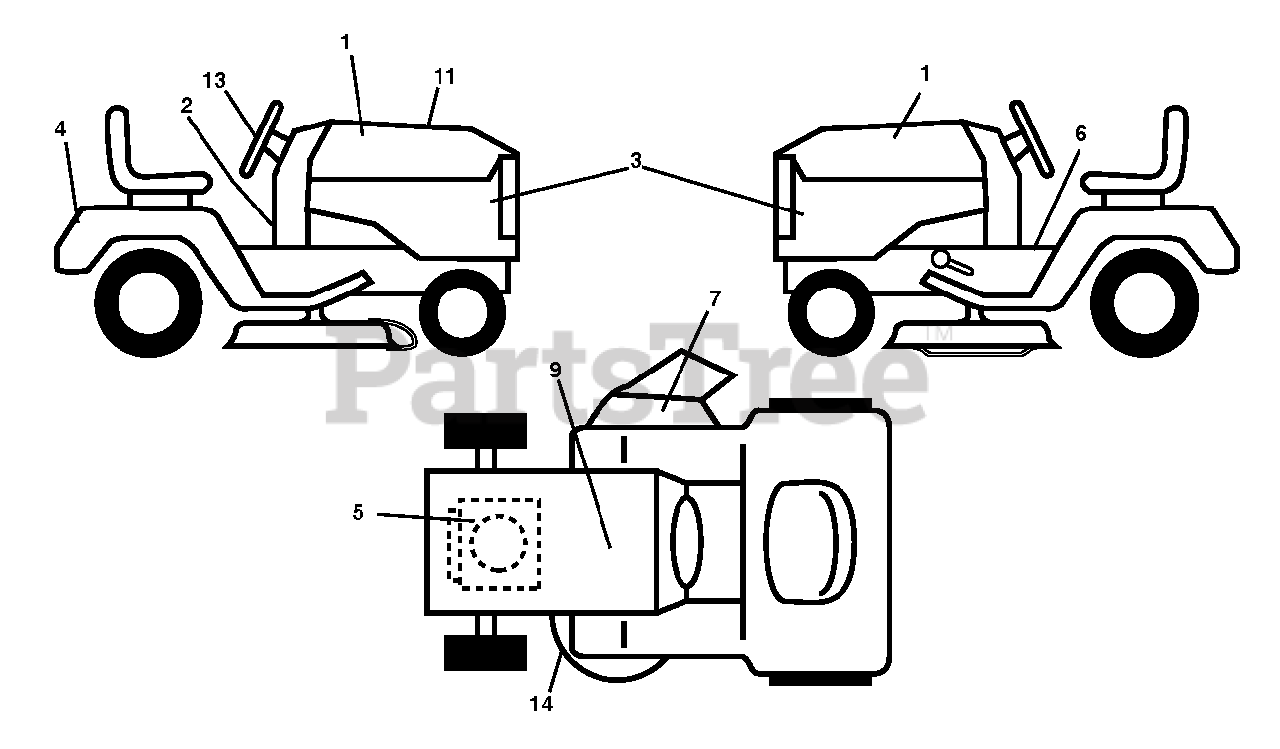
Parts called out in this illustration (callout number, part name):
1	DECAL.POULAN PRO.2015
2	DCL.WARNING.SPARK.IGNITION.CA
3	DECAL TRACTOR SIDE PANEL DECAL
4	DECAL.REARFNDR.POULAN PRO.2015
5	Decal, Engine BS 20INTK DOM 381707
6	DECAL.WARNING.2007.ENG/FR
7	DECAL, DECK DEFLECTOR, WARNING
9	DECAL BTRY SYMBOLS
11	DECAL DECAL.RPL.BSM40.INTK.TLW
13	DECAL.STRWHL.BLK.2014.PPRO
14	DECAL.V-BELT.SCH.42/46"MEC/ELE
